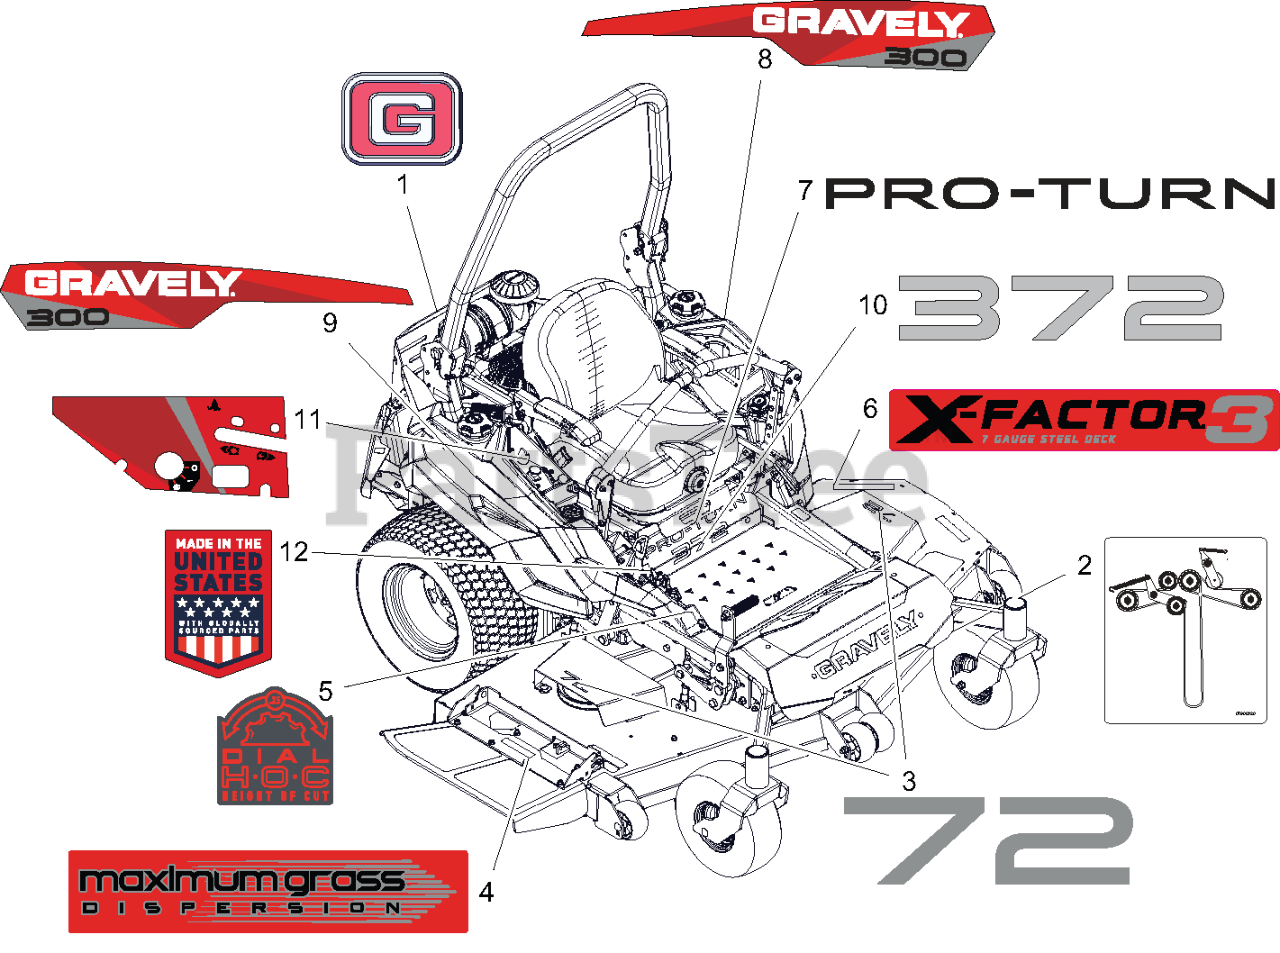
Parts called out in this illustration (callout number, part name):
1	DECAL, GRAVELY BRAND
2	DCL,BELT ROUTE-RH BK-SIDE IDLR
3	DECAL, DECK - 72
4	DECAL, DECK - MAX GRASS
5	DECAL, COVER - HOC
6	DECAL, DECK - X-FACTOR 3
7	DECAL, PRO TURN
8	DECAL- GRAVELY TANK - LH PT300
9	DECAL- GRAVLEY TANK - RH PT300
10	DECAL- 372
11	DECAL- CONTROL PANEL
12	DECAL- MADE IN USA
